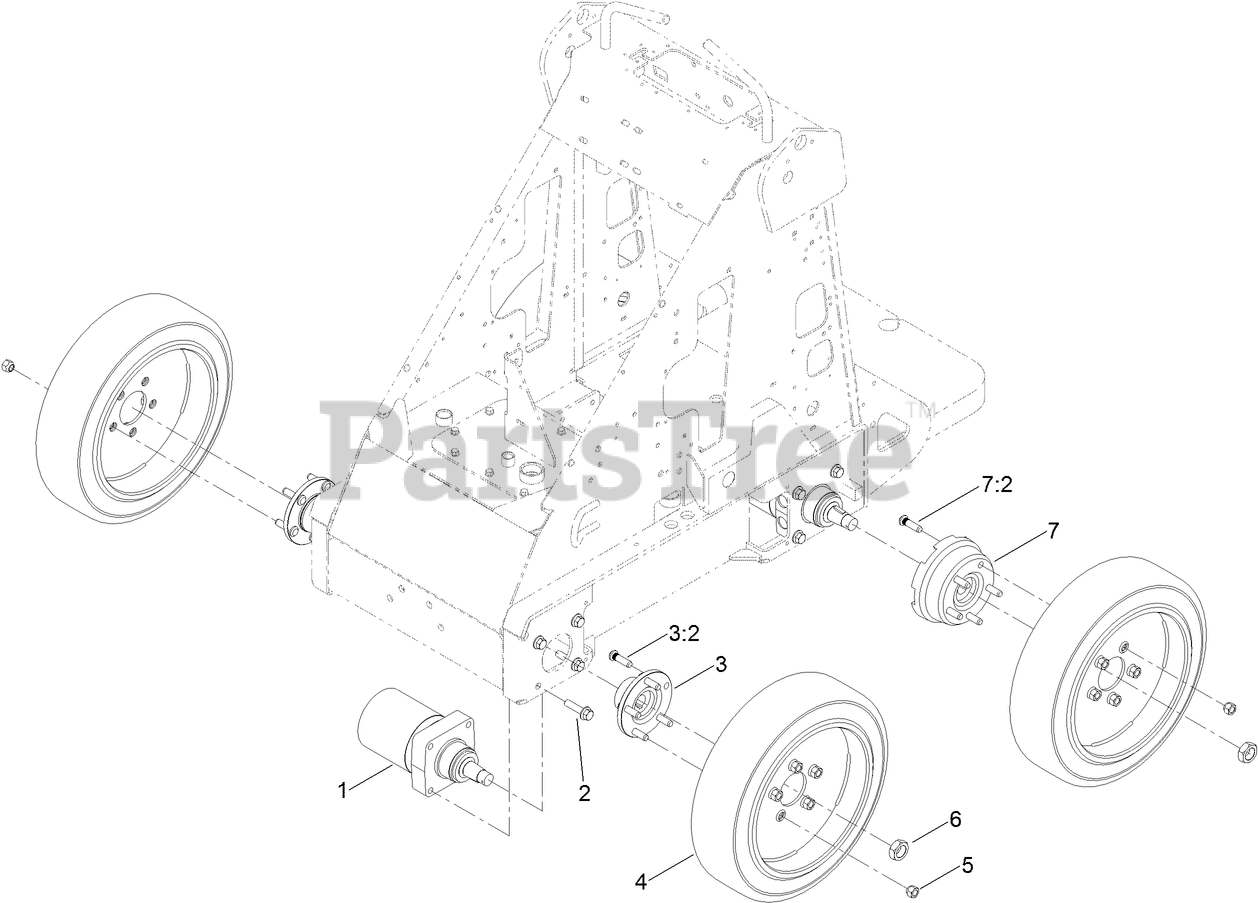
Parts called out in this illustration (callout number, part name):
1	HYD MOTOR ASM
2	SCREW-HHF
3	HUB ASM
3:2	STUD-TYPE, DRIVE
4	TIRE-SOLID
5	NUT-LUG
6	NUT-LOCK
7	WHEEL HUB ASM
7:2	STUD-TYPE, DRIVE
